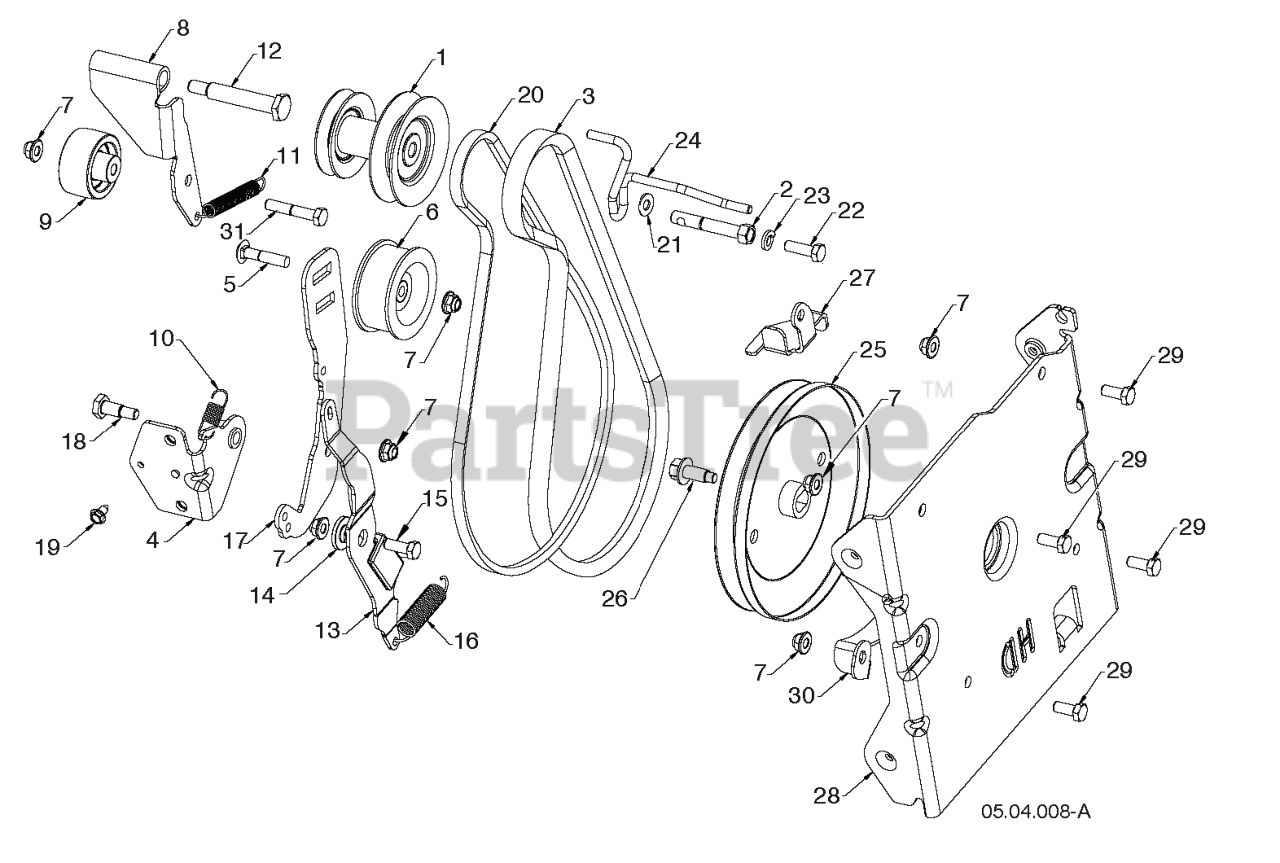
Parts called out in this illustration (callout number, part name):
1	PULLEY WELDMENT
2	BOLT.ENGINE.PULLEY
3	BELT 5L 39.15L
4	BRACKET WELDMENT, IDLER ARM ZI
5	BOLT 5/16-18 CARRIAGE 1.5L
6	PULLEY IDLER
7	NUTNYLOK.FLRANGE.5/16-18
8	ARM IDLER DRIVE WELDMENT_HOT
9	PULLEY.IDLER.FLANG.2.O/SPACER
10	SPRING IDLER RETURN
11	SPRING RETURN IDLER ARM
12	BOLT 5/16-24X2.25 HEX HEAD SHO
13	ARM IMPELLER BRAKE
14	BUSHING.BRAKE.ARM
15	BOLT
16	SPRING EXTENSION - BRAKE
17	ARM IDLER BLACK ZINC
18	SCREW HEX HEAD SHOULDER
20	BELT 3L 39.68; POLY CORD
21	WASHER M
22	SCREW 5/16-24 X .75 GR5
23	WASHER.LOCK.HVY.HLCL.SPR.5/16
24	GUIDE BELT - 3L FRICTION, 5L I
25	PULLEY IMPELLER DD 5L HD
26	SCREW FLANGE HEAD CAP WITH DOG
28	BRACKET AUGER HOUSING INTERFAC
29	BOLT.FIN.HEX.5/16-18X3/4
30	BRACKET.BELT.KEEPER.LOWER.BLAC
31	BOLT, HEX 5/16-18X1-3/4
